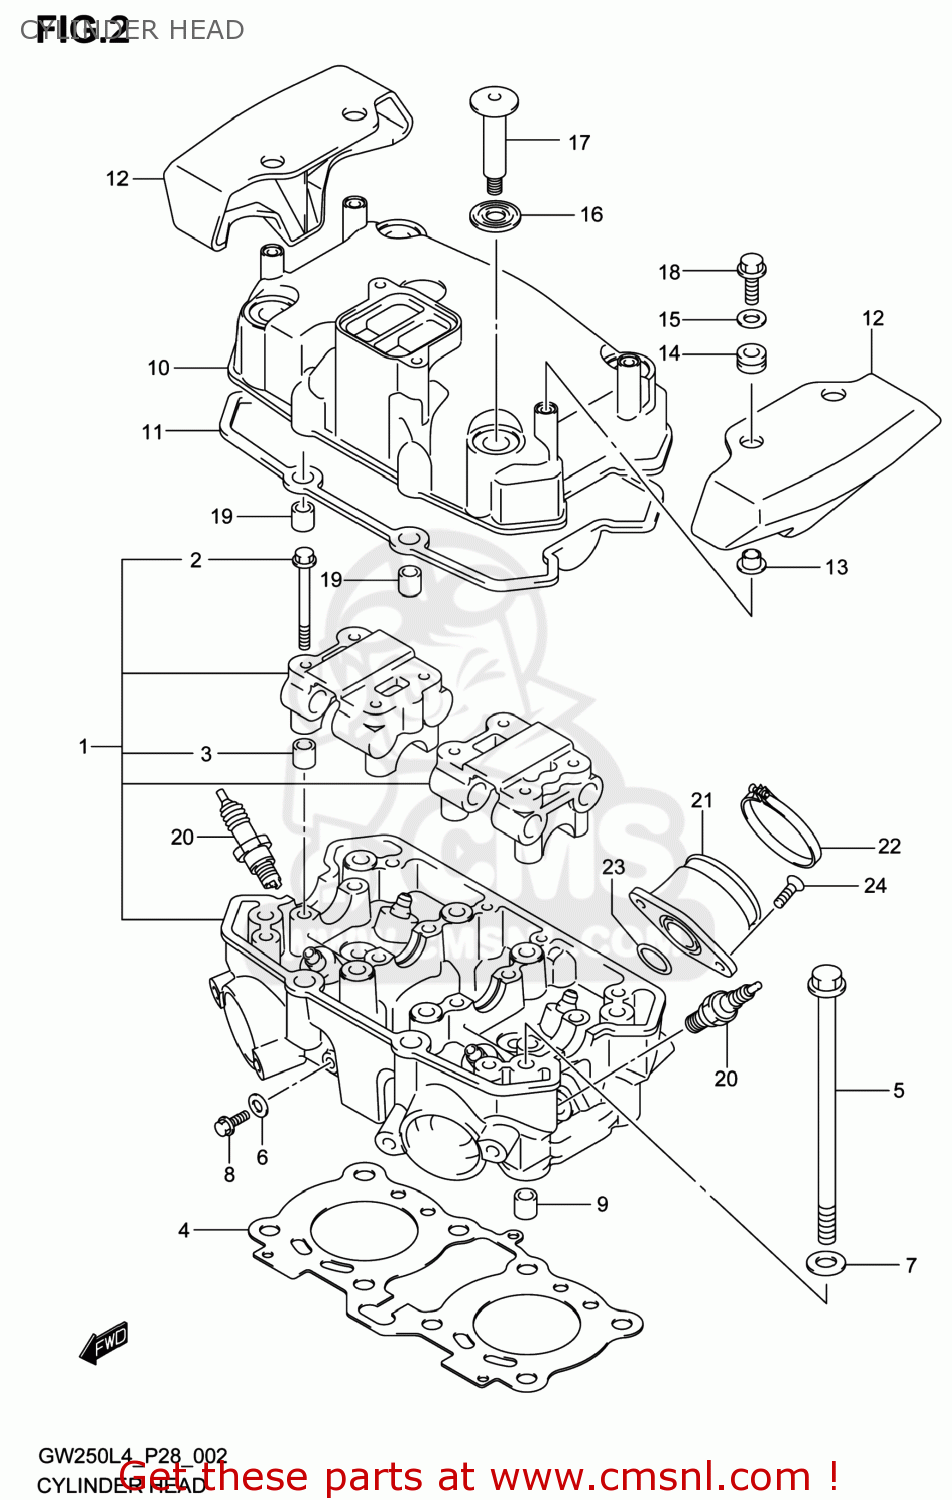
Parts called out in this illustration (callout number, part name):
1	HEAD ASSY,CYLINDER
2	BOLT(6X60)
3	PIN(8X11)
4	GASKET,CYLINDER HEAD (NAS)
5	BOLT(8X165)
6	GASKET(5.8X13X1.8) (NAS)
7	GASKET(8.5X17X2.3) (NAS)
8	BOLT
9	PIN
10	COVER,CYLINDER HEAD
11	GASKET,CYL HEAD COVER (NAS)
12	CAP,CYLINDER HEAD COVER
13	SPACER,HEAD COVER CAP
14	CUSHION,HEAD COVER CAP
15	WASHER(6.5X20X1.2)
16	WASHER,CYL HEAD COVER
17	BOLT(7X57)
18	BOLT
19	PIN
20	PLUG,SPARK(CR7E)
21	PIPE,INTAKE
22	CLAMP,INTAKE PIPE
23	O RING(D:2.3,ID:29.7)
24	SCREW
